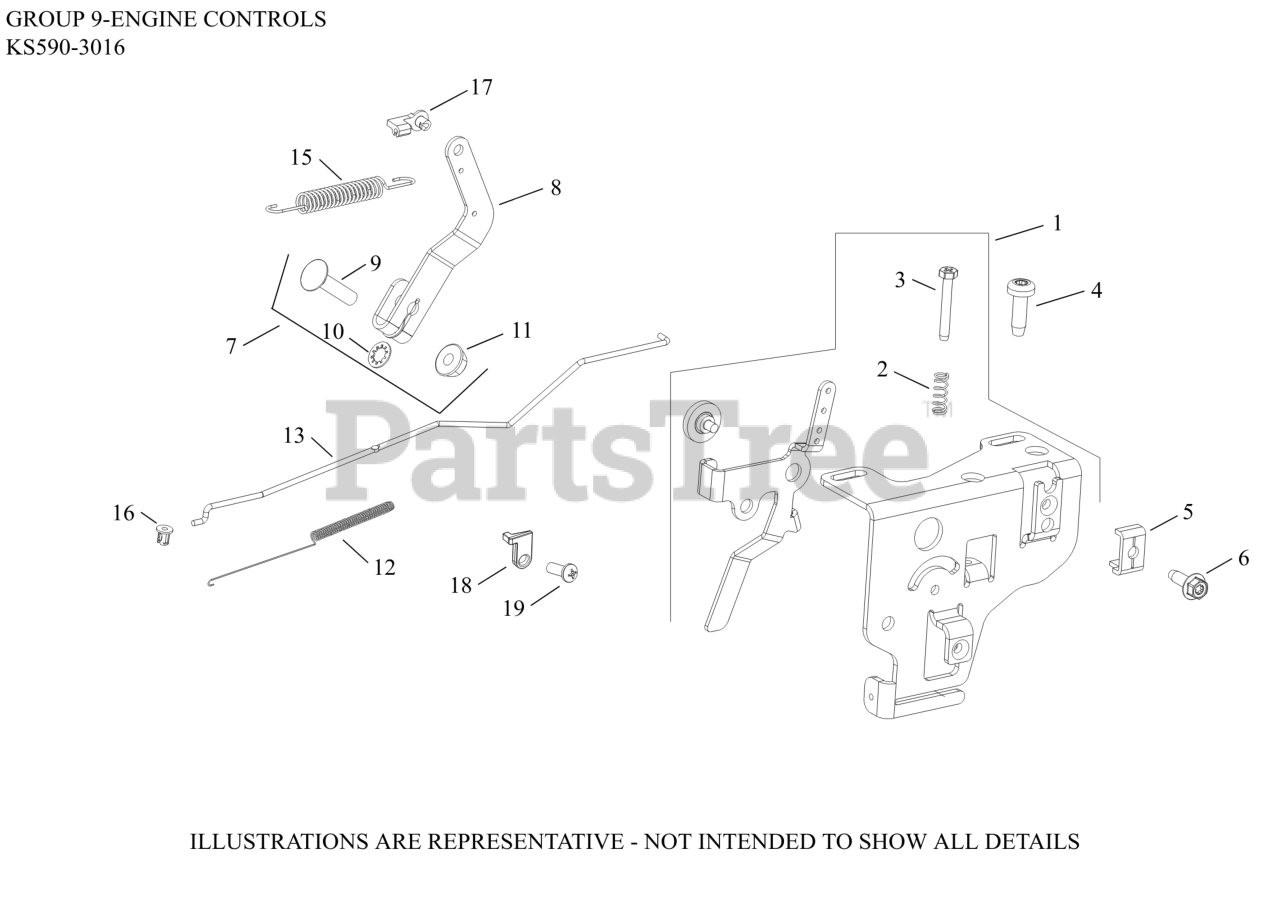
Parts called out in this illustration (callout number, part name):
1	CONTROL ASSY SPEED
2	SPRING, SPEED CONTROL
3	KIT, IDLE ADJ SCREW & SPRING
4	SCREW, THREAD FORMING
5	CLAMP, CABLE-(#2523753S)
6	SCREW, THREAD FORMING
7	LEVER, GOVERNOR ASSY
8	LEVER, GOVERNOR
9	BOLT, RD HD SQ NCK 1/4-20X1"
10	WASHER, INT TOOTH LOCK 1/4"
11	NUT, FLANGE 1/4-20
12	SPRING, LINKAGE
13	LINKAGE, THROTTLE
15	SPRING, GOVERNOR
16	BUSHING, LINKAGE RETAINING
17	BUSHING, THROTTLE LINKAGE
18	CLAMP, CHOKE WIRE HOLD DOWN
19	SCREW, SELF TAPPING
